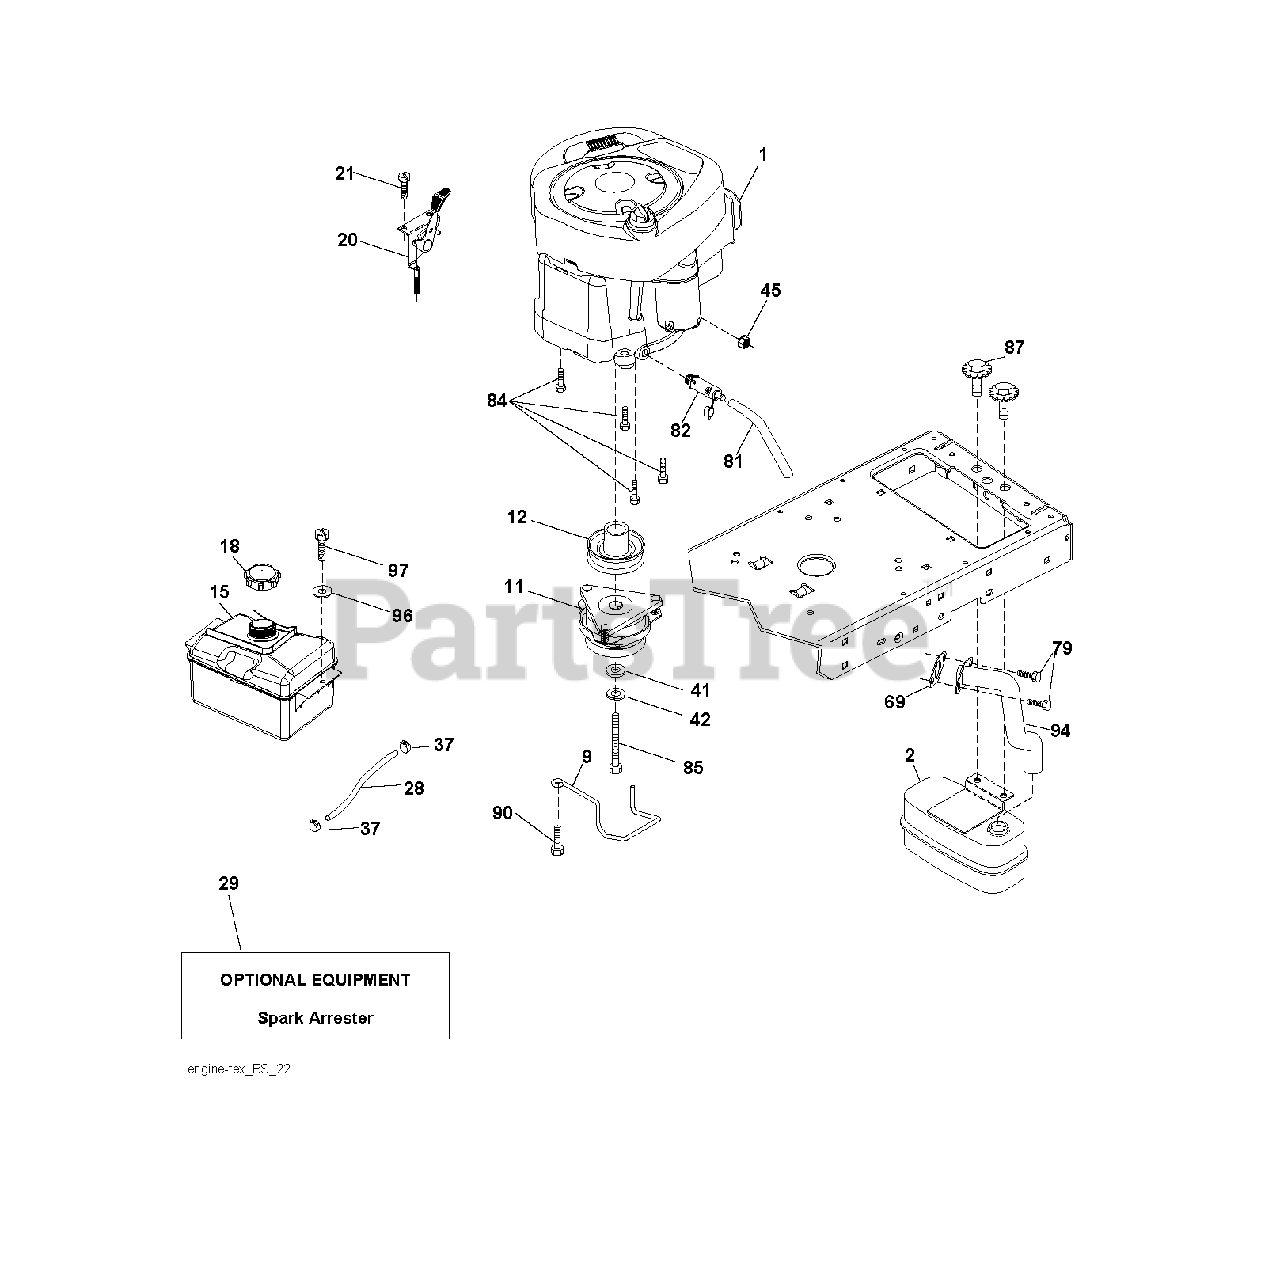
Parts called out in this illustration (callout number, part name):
2	MUFFLER.SINGLE.CYL.KOHL/B&S
9	KEEPER.BELT.ENGINE.4.2
11	CLUTCH
12	PULLEY.ENGINE.TUFFTORQ
15	TANK FUEL FRT 1.5 GAL
18	CAP.FUEL.2.25"VENTED"
20	CONTROL.TH/CK.C.
21	SCREW.#10 X 0.750.BOS THREAD
28	LINE.FUEL.20
29	ARRESTER SPARK (OPTIONAL)
37	HOSE CLAMP
42	LOCKWASHER
45	NUT
69	REPL BY 532 27 22-93
79	SCREW.SOCKET HD.5/16-1
81	TUBE, DRAIN OIL ASM.
82	PLUG DRAIN OIL EASY
84	SCREW.3/8-16
85	BOLT HEX 7/16-20X4-1/4"
87	BOLT, 5/16-18 X 1 3/4
90	SCREW 3/8-16X1
94	EXHAUST.TUBE.B&S.
96	WASHER
97	SCREW HEXWSHR 1/4-20X3/4
